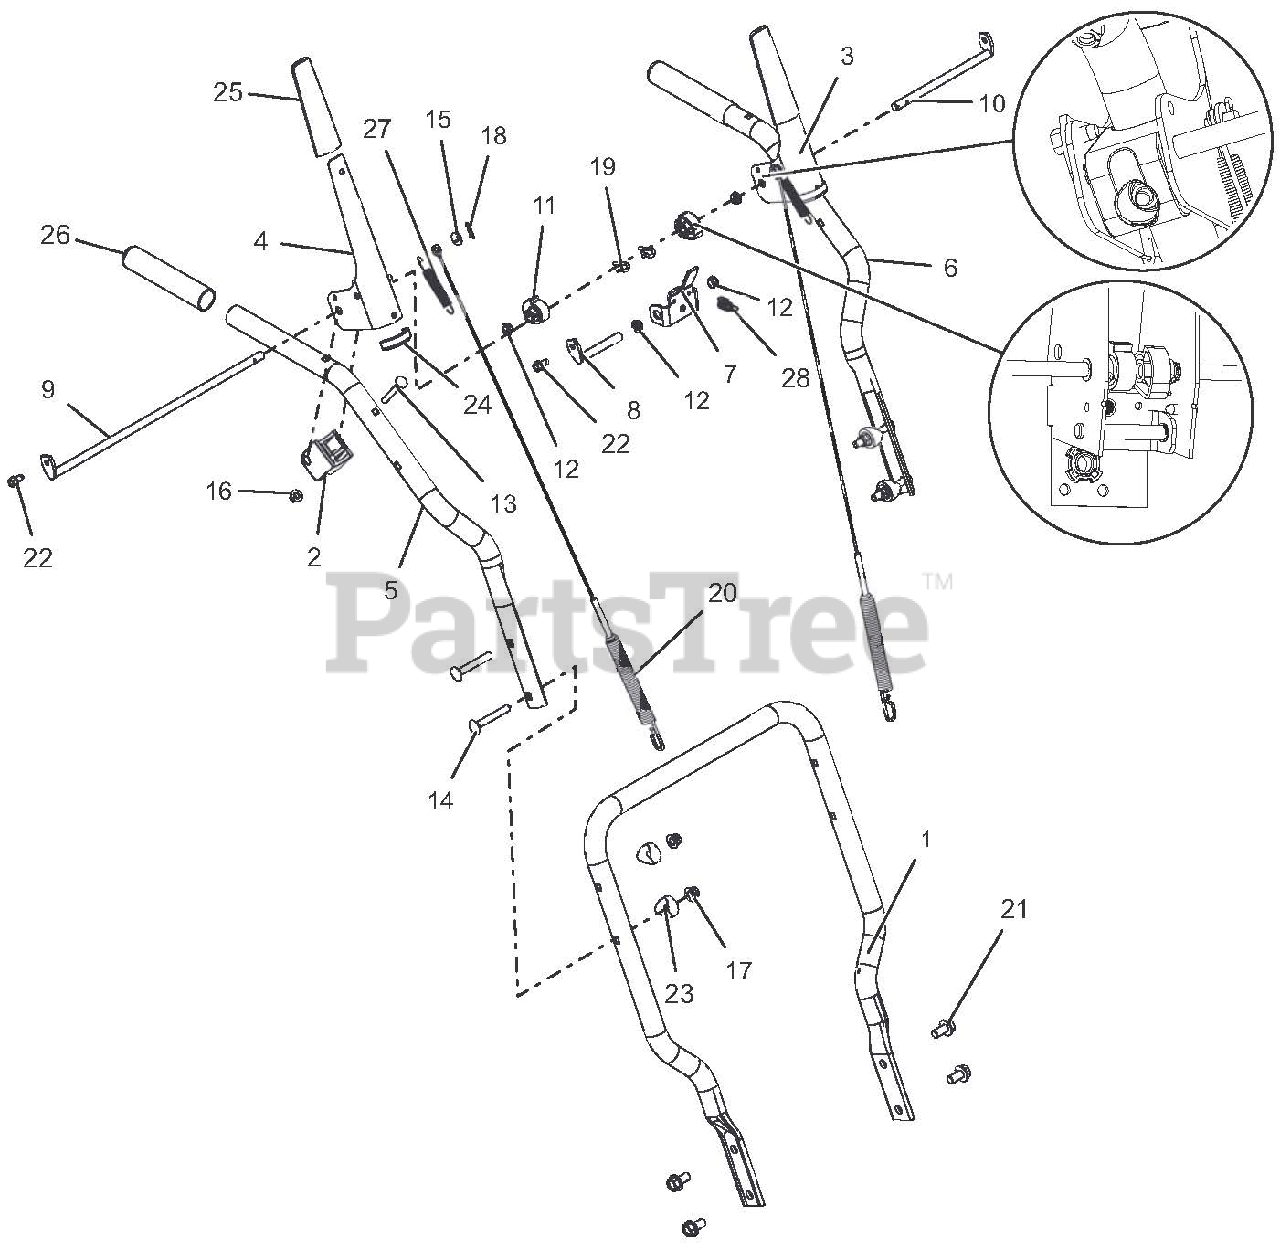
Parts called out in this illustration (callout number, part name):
1	HANDLEBAR, LOWER (COMPACT)
2	BLOCK, CLUTCH PADDLE
3	LEVER, CLUTCH-LH
4	LEVER, CLUTCH-RH
5	HANDLEBAR, UPPER - RH
6	HANDLEBAR, UPPER - LH
7	BRACKET, INTERLOCK ARM
8	ROD, PIVOT - INTERLOCK
9	ROD, PADDLE MOUNT - LONG
10	ROD, PADDLE MOUNT - SHORT
11	CAM, INTERLOCK
12	BUSHING, POLYLINER-.38 SNAPIN
13	BLT-RDHDXLSQNK .25-20X2.0 G5YZ
14	@BLT-RDHDSQNK .31-18X2.25 G5YZ
15	@WSHR-FL-STL.281X.62X.065 YWZC
16	@NUT-LK-TOP-FLG .25-20 YWZC
17	@NUT-LK-NYL-FLG .31-18 YWZC
18	PIN-HAIR INT .06X.18X.77
19	PIN, SPRING CLIP
20	CABLE, AUGER & UPPER TRACTION
21	BLT-SERHFWH .38-16X.75 YWZC
22	SCR-TAP .25-20X.50 HWH TR YWZ
23	SPACER, HANDLEBAR
24	EDGING, CLUTCH PADDLE - 2.00"
25	CLUTCH PADDLE SLEEVE - GRAY
26	HANDLE GRIP
27	SPRING, EXTENSION
28	SPRING-EXT .047X.438X1.45
